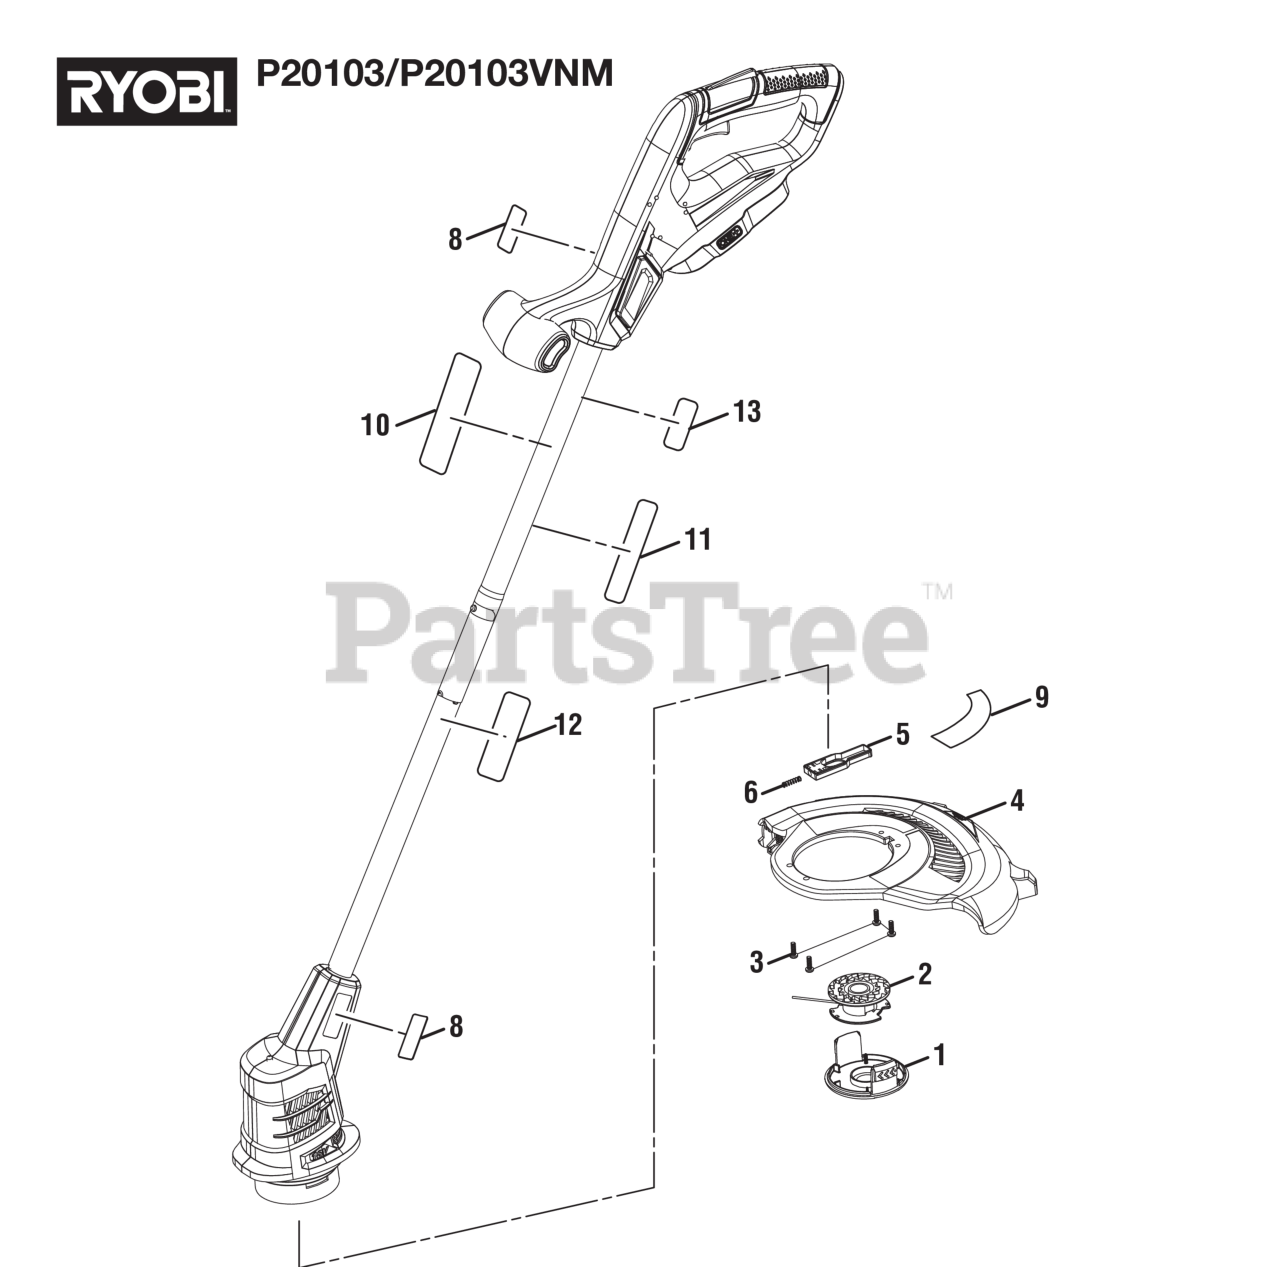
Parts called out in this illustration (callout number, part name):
1	Spool Cap (AC14HC)
2	Spool w/Line
3	Screw (M4 x 12 mm, Pan Hd.)
4	Guard w/Blade Assembly
5	Slider Assembly
6	Compression Spring (Internal Tooth)
8	Logo Label
9	Autofeed No Bump Guard Label
10	Warning Icon Label
11	Warning Label (French/Spanish)
12	Data Label
